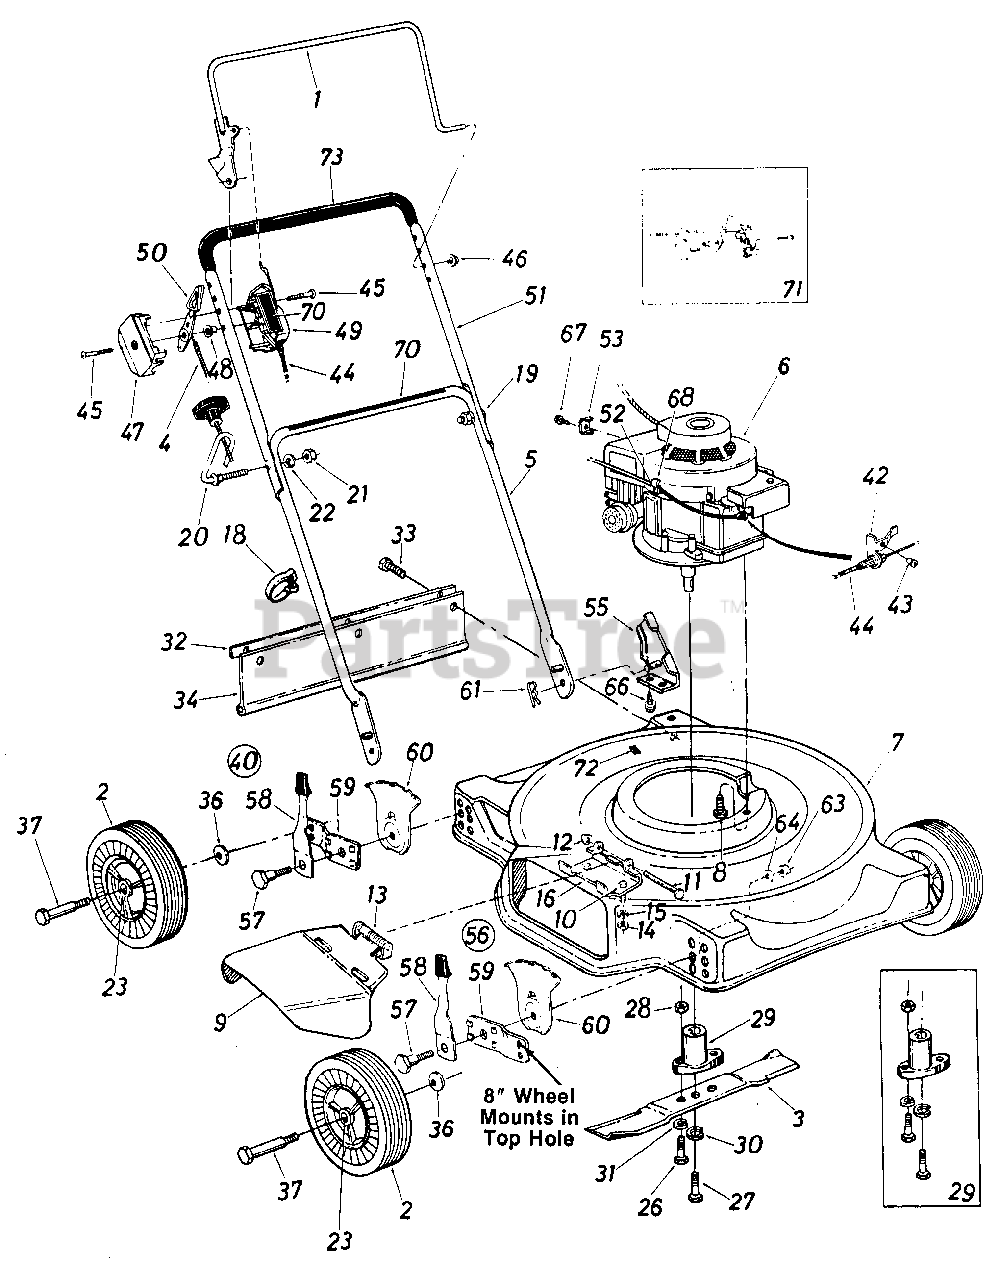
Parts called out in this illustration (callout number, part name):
1	Control Handle Assy'y-R.H.
2	Wheel Ass'y. Comp.
4	Throttle Control Wire 39.0"
5	Lower Handle
6	Engine
7	20" Deck Ass'y.
8	Hex Wash. Hd. TT-Tap Scr. 3/8-16 x 1.00" Lg.
9	Chute Deflector Ass'y.
10	Hex Bolt 1/4-20 x .50" Lg.*
11	Hinge Pin 1/4" Dia. x 3.88 Lg.
12	Push Cap .25" Rod
13	Torsion Spring
14	Hex Nut 14-20 Thd.*
15	L-Wash. 1/4" I.D.*
16	Deflector Hinge Plate
19	Curved Carriage Bolt 5/16-18 x 1.38" Lg.
20	Rope Guide Bolt
21	Hex Nut 5/16-18 Thd.*
22	L-Wash. 5/16" I.D.*
26	Hex Bolt 5/16-24 x 1.00" Lg.
27	Hex Bolt 3/8-24 x 2.25" Lg. (Grade 5)
28	Hex Nut 5/16-24 Thd.*
29	Blade Adapter Kit
30	L-Wash. 3/8" I.D. H.D.
31	L-Wash. 5/16" I.D.*
32	Retainer Strip
33	Hex AB-Tap Scr. 1/4 x .62" Lg.*
34	Rear Flap Ass'y.
36	Bell-Wash. .400" I.D. x .88" O.D.
40	Height Adjuster Ass'y. Comp. L.H.
42	Cable Bracket
43	Pop Rivet .156" Gia. x .379
44	Control Cable 49"
45	Truss Mach. Scr. #12 x 1.50"
46	Cap Speed Nut 5/16" Rod
47	Control Panel Half
48	Control Disc Pin
49	Clutch Panel Half
50	Throttle Control Lever
51	Upper Handle
52	Hex "B" Tap Scr. #10 x .38"
53	Casing Clamp
55	Handle Mount Brkt. Ass'y. L.H.
56	Height Adjuster Ass'y. Comp. R.H.
57	Shoulder Bolt .500" Dia. x .357
58	Spring Lever Ass'y. w/ Knob
59	Pivot Bar
60	Index Plate
61	Hairpin Cotter
63	Hex Nut 3/8-16 Thd.*
64	Bell-Wash. .39" I.D. x 1.4" O.D.
66	Hex Wash. Hd. Self-Tap Scr. 5/16-18 x .50" Lg.
67	Hex Wash. Hd. AB-Tap Scr. #8 x .38" Lg.
68	Cable Clip
70	Control Labels
71	Kit Control Housing Comp.
72	Plastic Plug
73	Grip
8072-190-5	Hardware Pack
